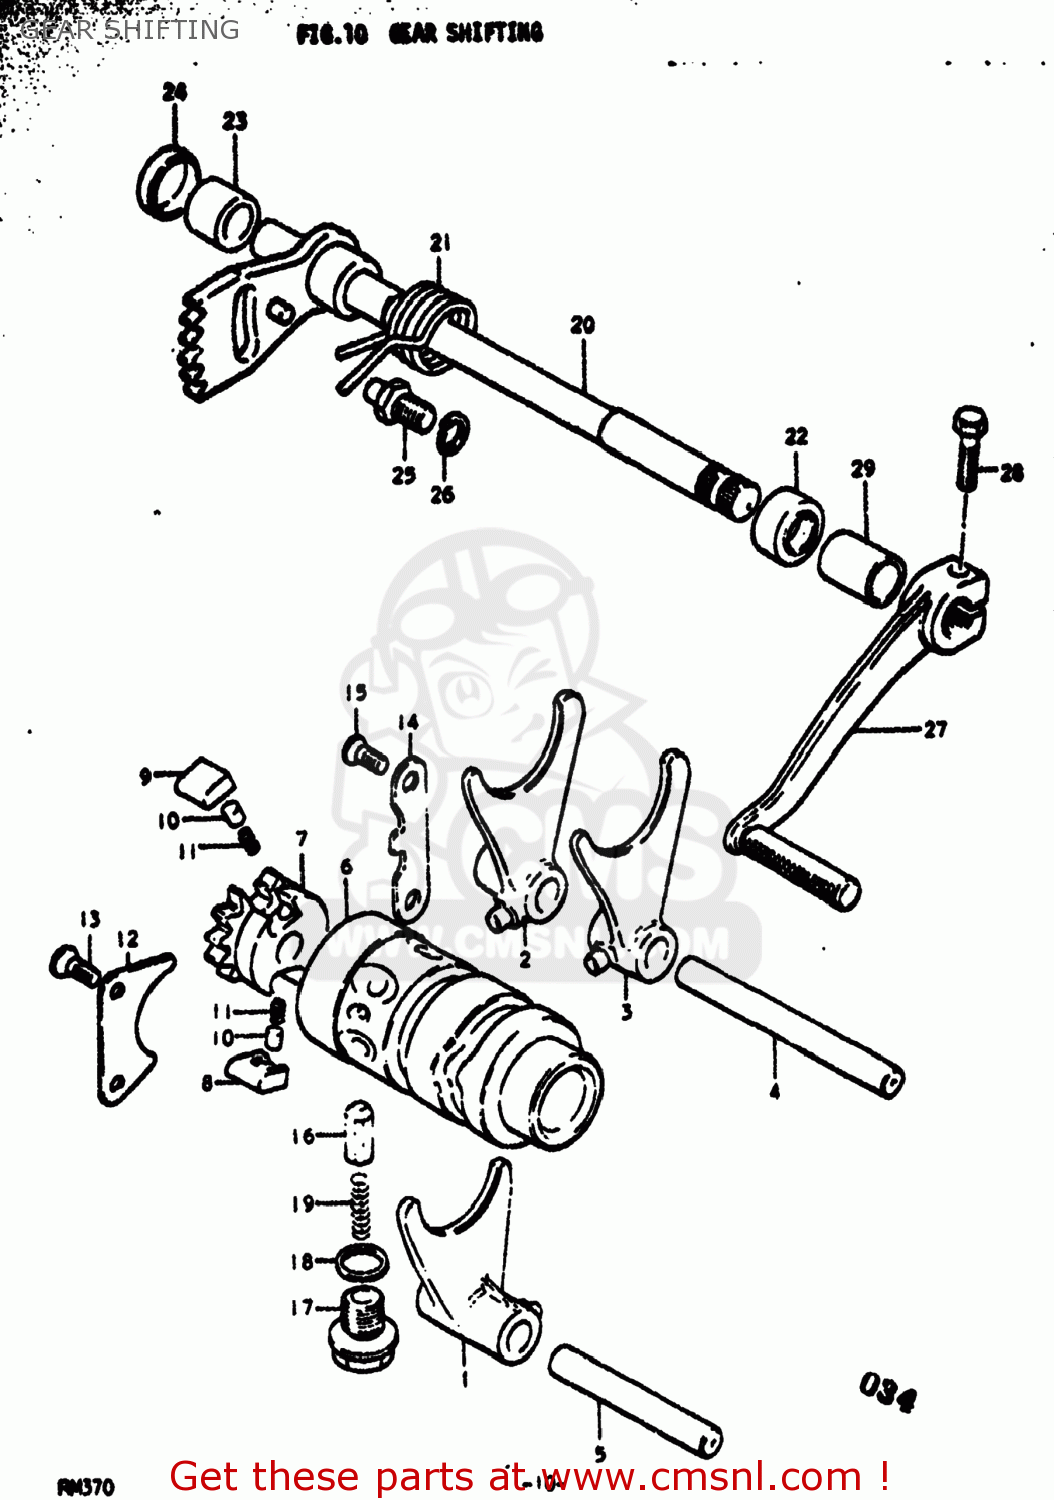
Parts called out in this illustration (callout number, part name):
1	FORK,GEAR SHIFT NO.1
2	FORK,GEAR SHIFT NO.2
3	FORK,GEAR SHIFT NO.3
4	SHAFT,GEAR SHIFT FORK
5	SHAFT,GEAR SHIFT FORK
6	CAM,GEAR SHIFT
7	RETAINER,GEAR SHIFT CAM
8	PAWL,GEAR SHIFT NO.1
9	PAWL,GEAR SHIFT NO.2
10	PIN(5X8)
11	SPRING
12	LIFTER,GEAR SHIFT PAWL
13	SCREW
14	STOPPER,GEAR SHIFT POLE
15	SCREW
16	STOPPER,GEAR SHIFTING
17	BOLT,GEAR SHAFT CAM STOPPER
18	GASKET 14.2X20.5X1.2 (NAS)
19	SPRING
20	SHAFT,GEAR SHIFT
21	SPRING
22	OIL SEAL
23	SPACER (12.2X20X13)
24	PLUG
25	STOPPER,GEAR SHIFT CAM
26	LOCK WASHER
27	LEVER ASSEMBLY,GEAR SHIFTING
28	BOLT
29	CUSHION
